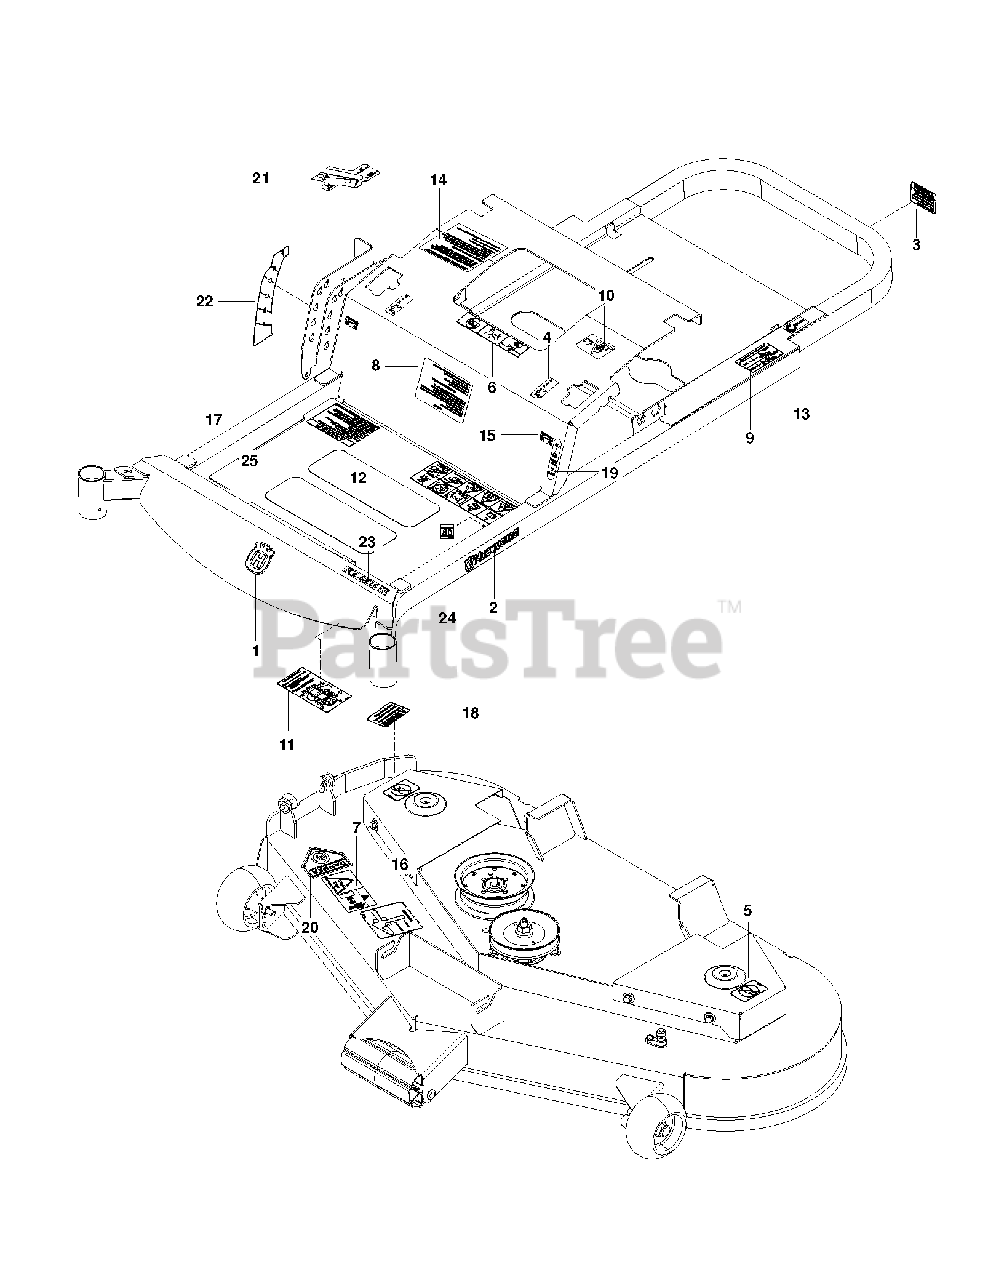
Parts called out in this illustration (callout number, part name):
1	DECAL.AUGER.HUSQ.CROWN.SNOW
2	RP.DECAL.BADGE.170MM.TEXTLOGO
3	DECAL, PROP. 65
4	DECAL, MOTION CONTROL
5	DECAL, NO STEP
6	EURO DECAL-BATTERY WARNIN6
7	DECAL, EURO SEVERING
8	DECAL, START
9	DECAL, DO NOT TOW
10	DECAL, EXITING MOWER
11	DECAL, SERVICE
12	DECAL, SAFETY WARNING
13	DECAL, ECM, AUSTRALIA
14	DECAL, CUSTOMER RESPNSIBILITY
15	DECAL, F.S.T.
16	DECAL, BELT ROUTING
17	DECAL, WARNING
18	DECAL, CAUTION
19	DECAL, PARK BRAKE
20	DECAL, CPSC
21	DECAL, CTRL PANEL, HUSQ
22	DECAL, DECK HEIGHT, HUSQ
23	DECAL.ZTR.RZ4824TF.HUSQVARNA
24	DECAL 80 DBA
25	ANTI-SKID PAD
